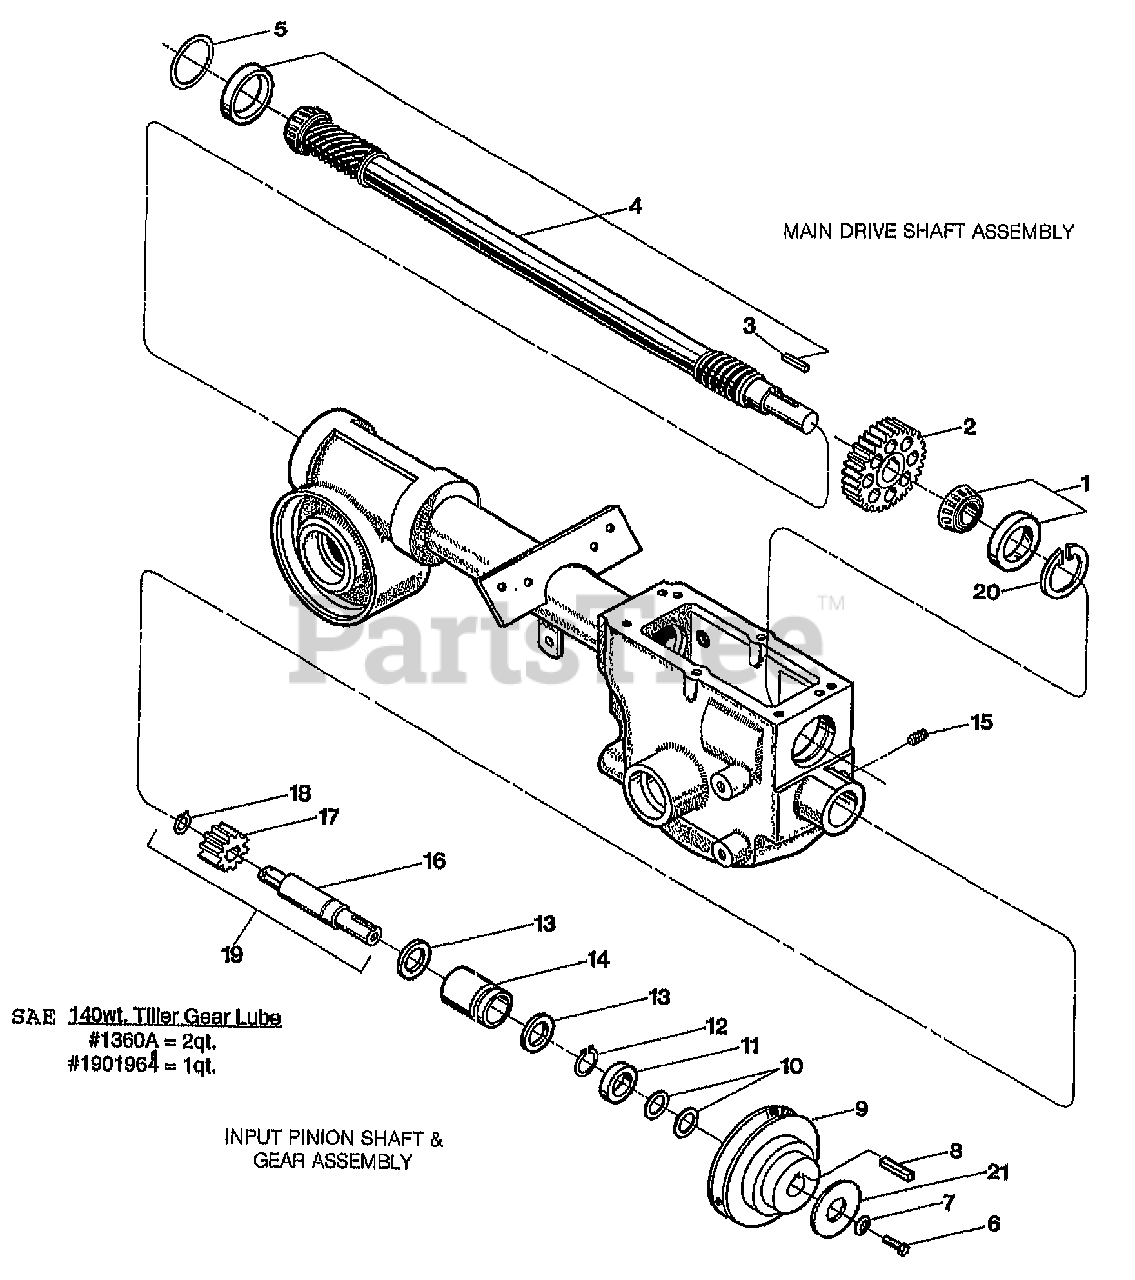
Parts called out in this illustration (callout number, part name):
1	KIT-BRG CONE&RACE-DRIVESHAFT (FRONT OF DRIVE SHAFT)
2	GEAR-SPUR 30 TEETH
3	KEY-.188 SQX1.0
4	KIT-DRIVESHAFT
4	KIT-DRIVESHAFT SMFR
5	SHIM-1.75X1.5X.01
5	SHIM-1.75X1.5X.03
5	SHIM-1.75X1.5X.005
6	SCR-HH 5/16-24X.75 G5 ZP
7	WASHER-.827X.331X.098
8	KEY-.188 SQX1.0
9	PULLEY-TRANS MACH
10	WASHER # .875 X .65 X .06
11	SEAL-PINION SHAFT PT/85030/00
12	RING-RETAIN EXT .707 ID (SNPA RING)
13	WASHER-1.022X.752X .059
14	BUSHING-1.24X.75X1.8 GRVD
15	SCR-SS 5/16-18X.375
16	SHAFT-PINION(P-V)
17	GEAR-PINION P/M
18	RING-BOWED EXT .461 ID
19	PINION W/GEAR&SNAP RING (INCL. 16-18)
20	RING-RETAINING 5000-181
21	WASHER-2.5X.316X.06
